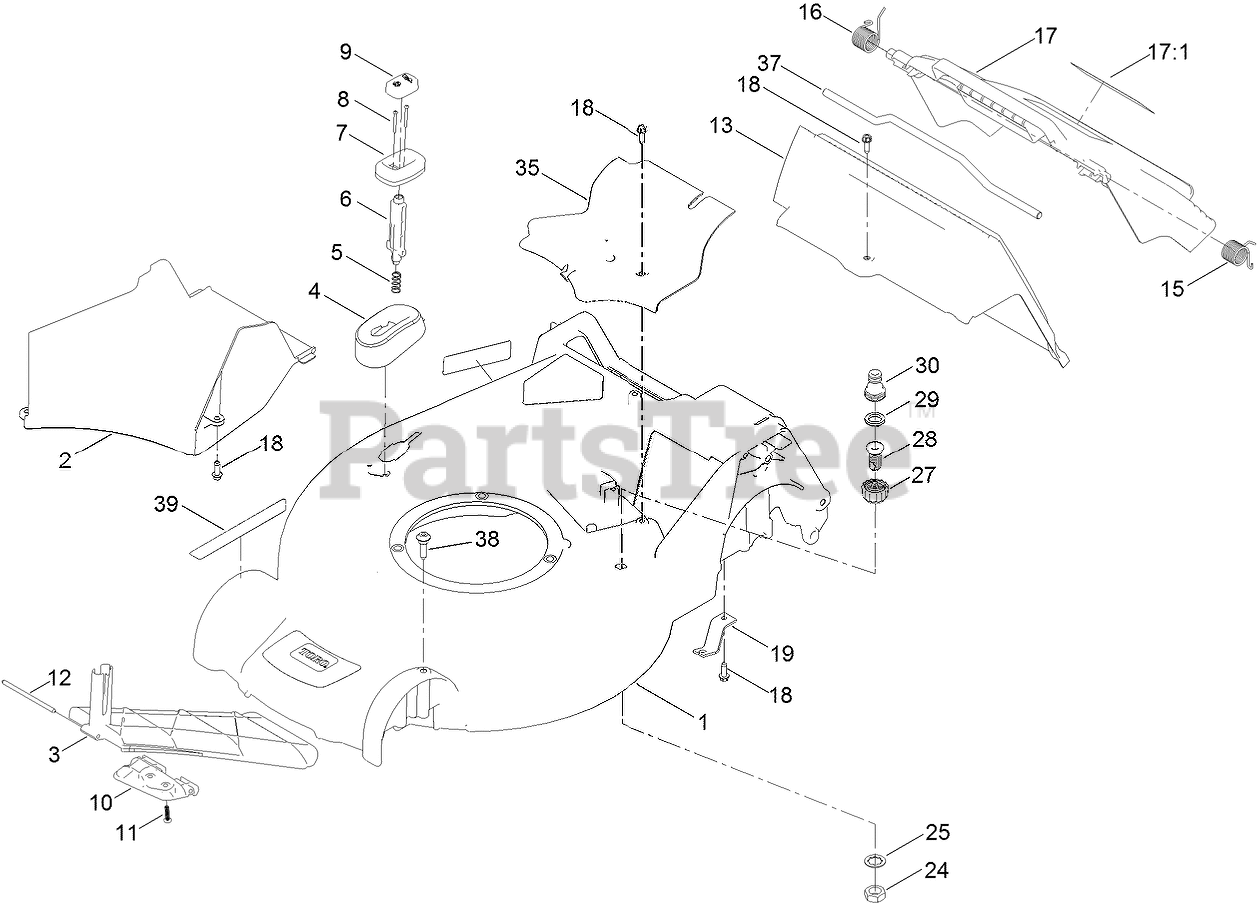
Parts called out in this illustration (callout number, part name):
1	HOUSING ASM
2	RAMP-DISCHARGE
3	DOOR-RECYCLE
4	COVER-DOOR, RECYCLE
5	SPRING-COMPRESSION
6	LATCH-RECYCLE
7	HOUSING-KNOB
8	SCREW-TORX, PAN HEAD
9	KNOB-RECYCLE
10	HINGE-DOOR, RECYCLE
11	SCREW-PLASTITE
12	PIN-HINGE
15	SPRING-TORSION
16	SPRING-TORSION
17	REAR DOOR ASM
17:1	DECAL-WARNING
18	SCREW-HWHTF
19	BRACKET-TRACTION CABLE
24	NUT-JAM
25	WASHER-LOCK, INT TOOTH
27	COUPLING-HOSE, WASHOUT PORT
28	PORT-WASHOUT
29	WASHER-SEAL, WASHOUT PORT
30	ADAPTER-CONNECT, QUICK
35	COVER-BELT
37	ROD-DEFLECTOR
38	SCREW-SHOULDER, BHTF
39	DECAL-HOC
